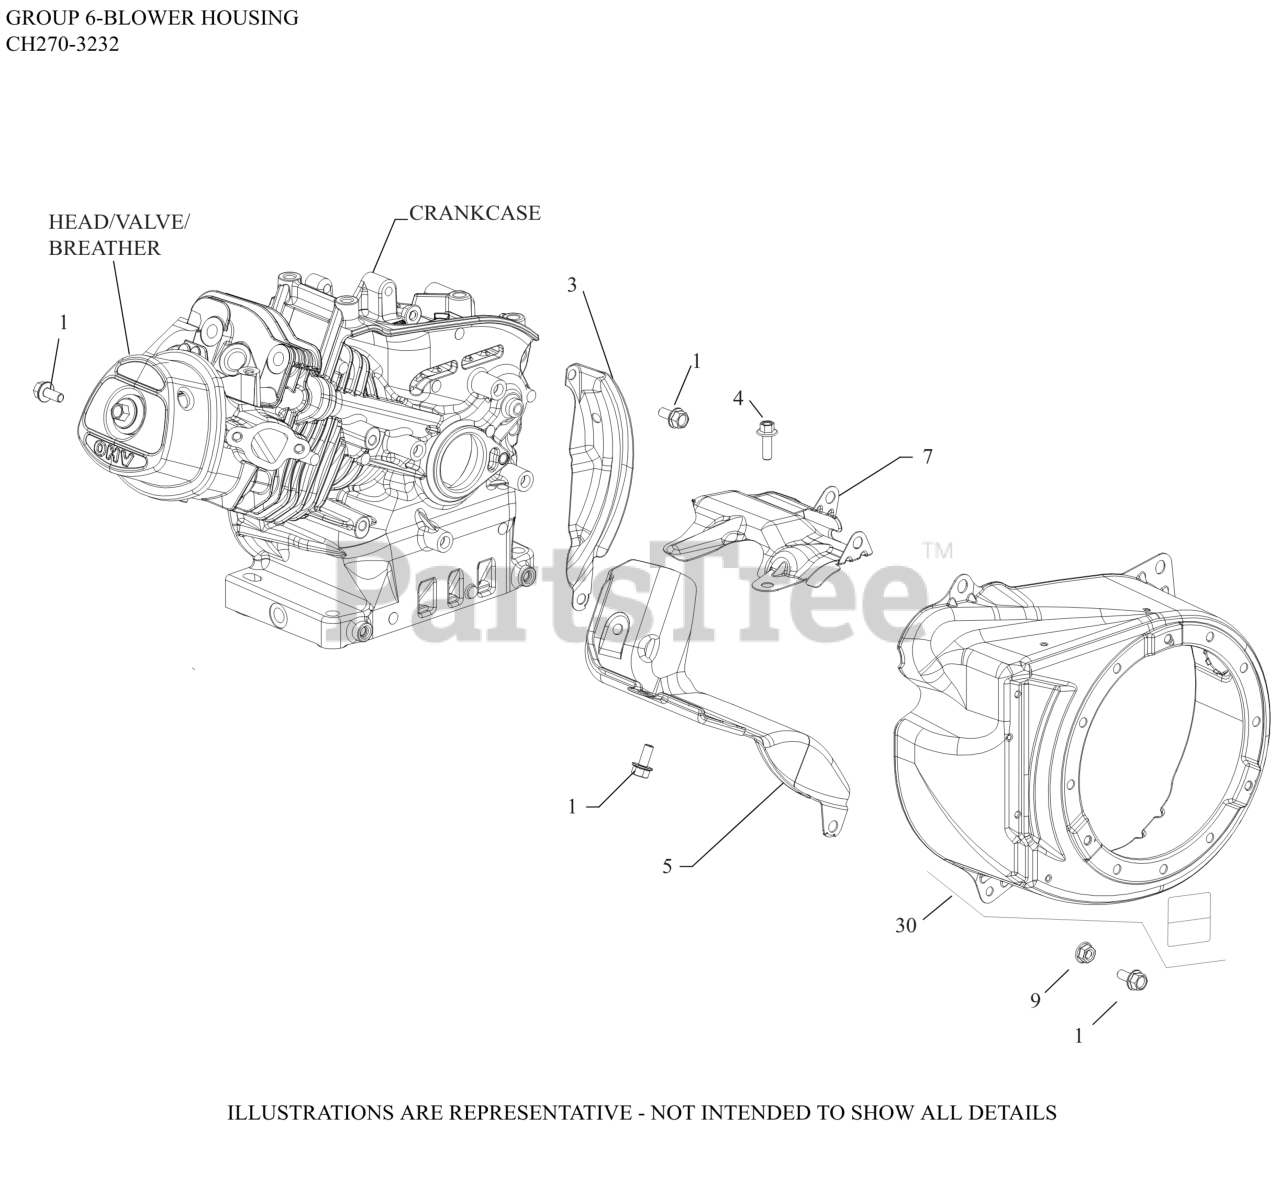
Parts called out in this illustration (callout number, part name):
1	SCREW, HEX FLANGE (M6)-USE 25 086 433-S
3	SHIELD, FLYWHEEL
4	SCREW, M6 X18
5	SHIELD, CYLINDER HEAD
7	SHIELD, UPPER HEAT
9	NUT, HEX FLANGE (M6) - USE 14 100 16-S
30	KIT, BLOWER HOUSING
